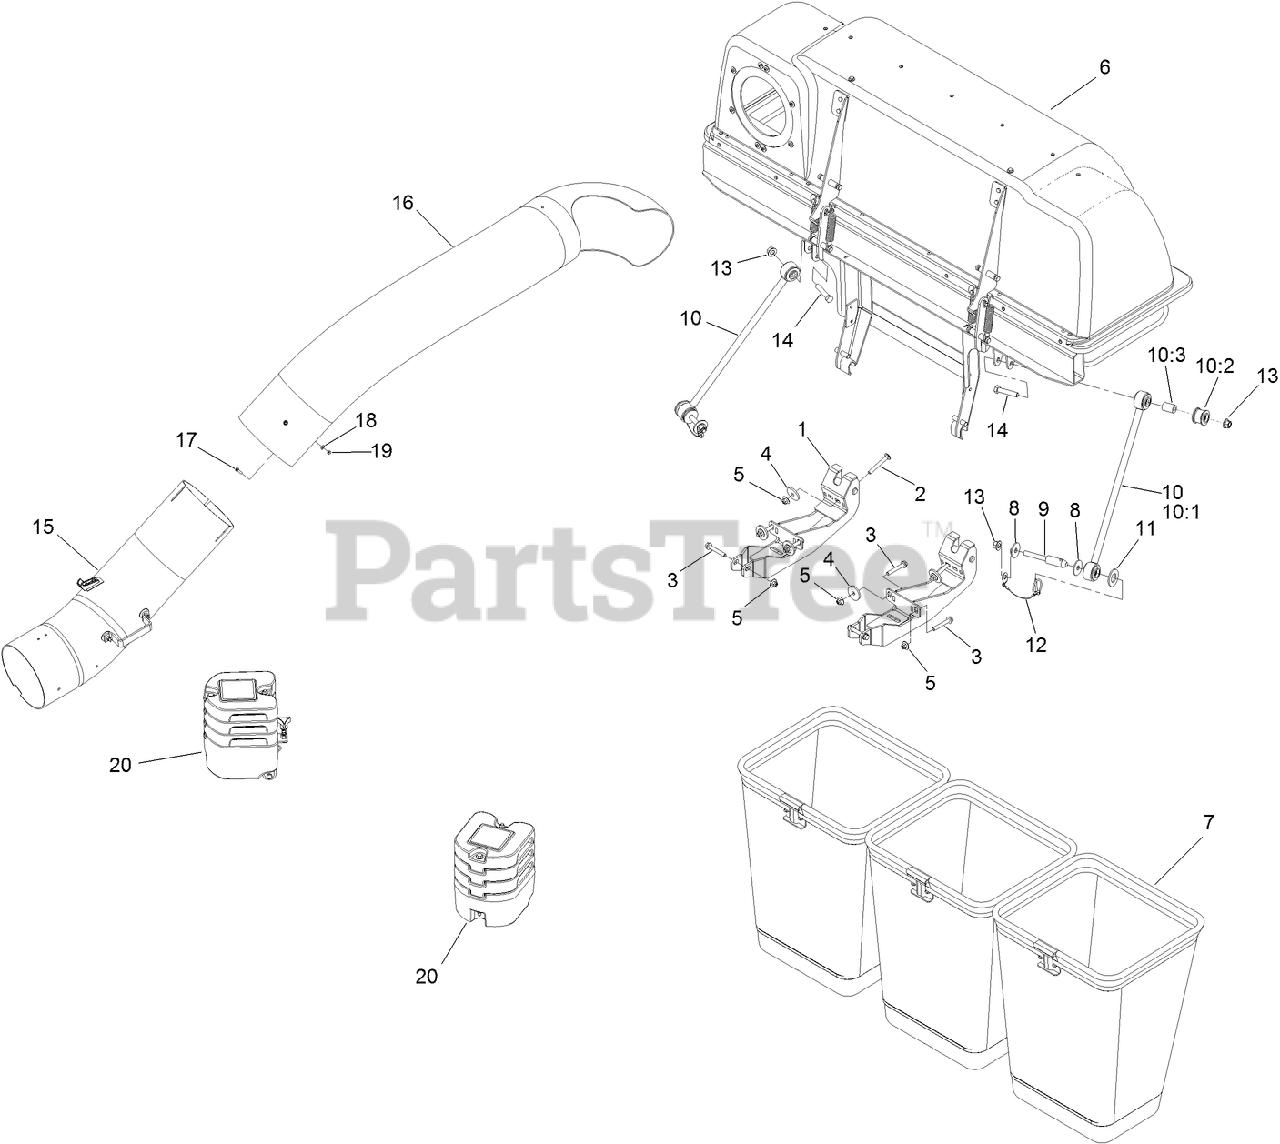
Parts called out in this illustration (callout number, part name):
1	MOUNT-BAGGER, LOWER
2	SCREW-CARR
3	SCREW-HHF
4	WASHER-PLAIN
5	NUT-FLANGE, NI
6	3-BAG HOOD ASM
7	BAG AND FRAME ASM
8	WASHER-THRUST
9	PIN-BAGGER BRKT
10	SUPPORT ROD ASM
10:1	ROD-PANHARD
10:2	BUSHING-RUBBER
10:3	SPACER
11	WASHER-FLAT
12	PIN-MOUNT, BAGGER
13	NUT-LOCK
14	SCREW-HH
15	LOWER TUBE ASM
16	TUBE-UPPER
17	SCREW-HWH
18	WASHER-FLAT
19	NUT-LOCK, NI
20	CASTER WEIGHT ASM
